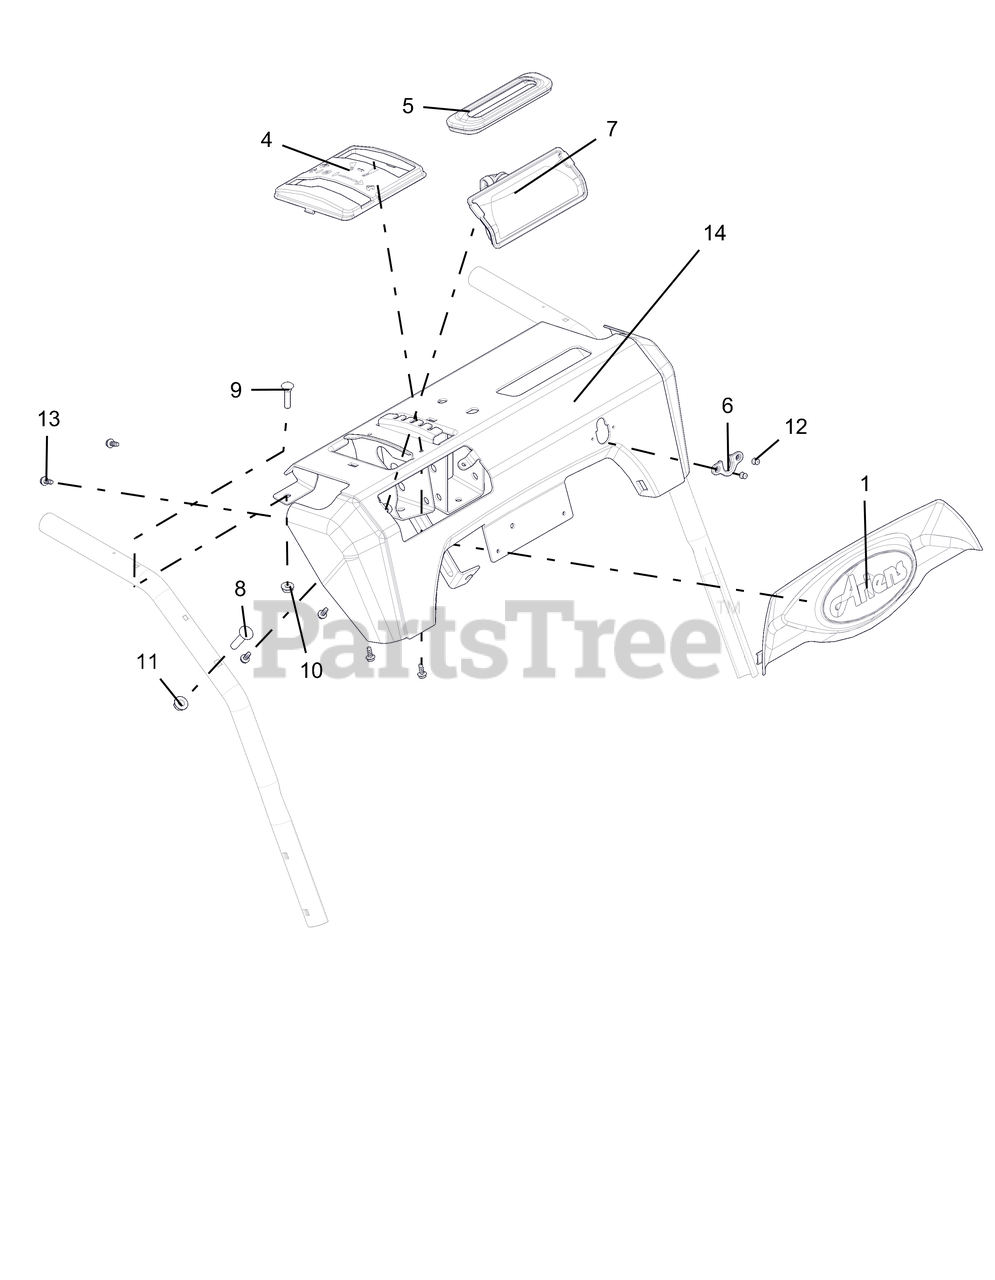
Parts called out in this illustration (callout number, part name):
1	DASH BEZEL, ARIENS LOGO - PRO
4	SHIFT BEZEL W/ NEUTRAL
5	GROMMET, BOOT, QUICK TURN
6	GROMMET, CABLE, QUICK TURN 2
7	HEADLIGHT ASY, HALO 20W 2SHOT
8	@BLT-RDHDSQNK .31-18X1.50 G5YZ
9	BLT-RDHDXLSQNK.25-20X1.25 G5ZC
10	@NUT-LK-CTR-FLG .25-20 YWZC
11	@NUT-LK-TOP-FLG .31-18 YWZC
12	RVT-POP #43 .125X.313 STL ZINC
13	SCR-TAP #10X.50 BOSS INDHXHD
14	KIT, DASH PANEL W/DECAL HYD
